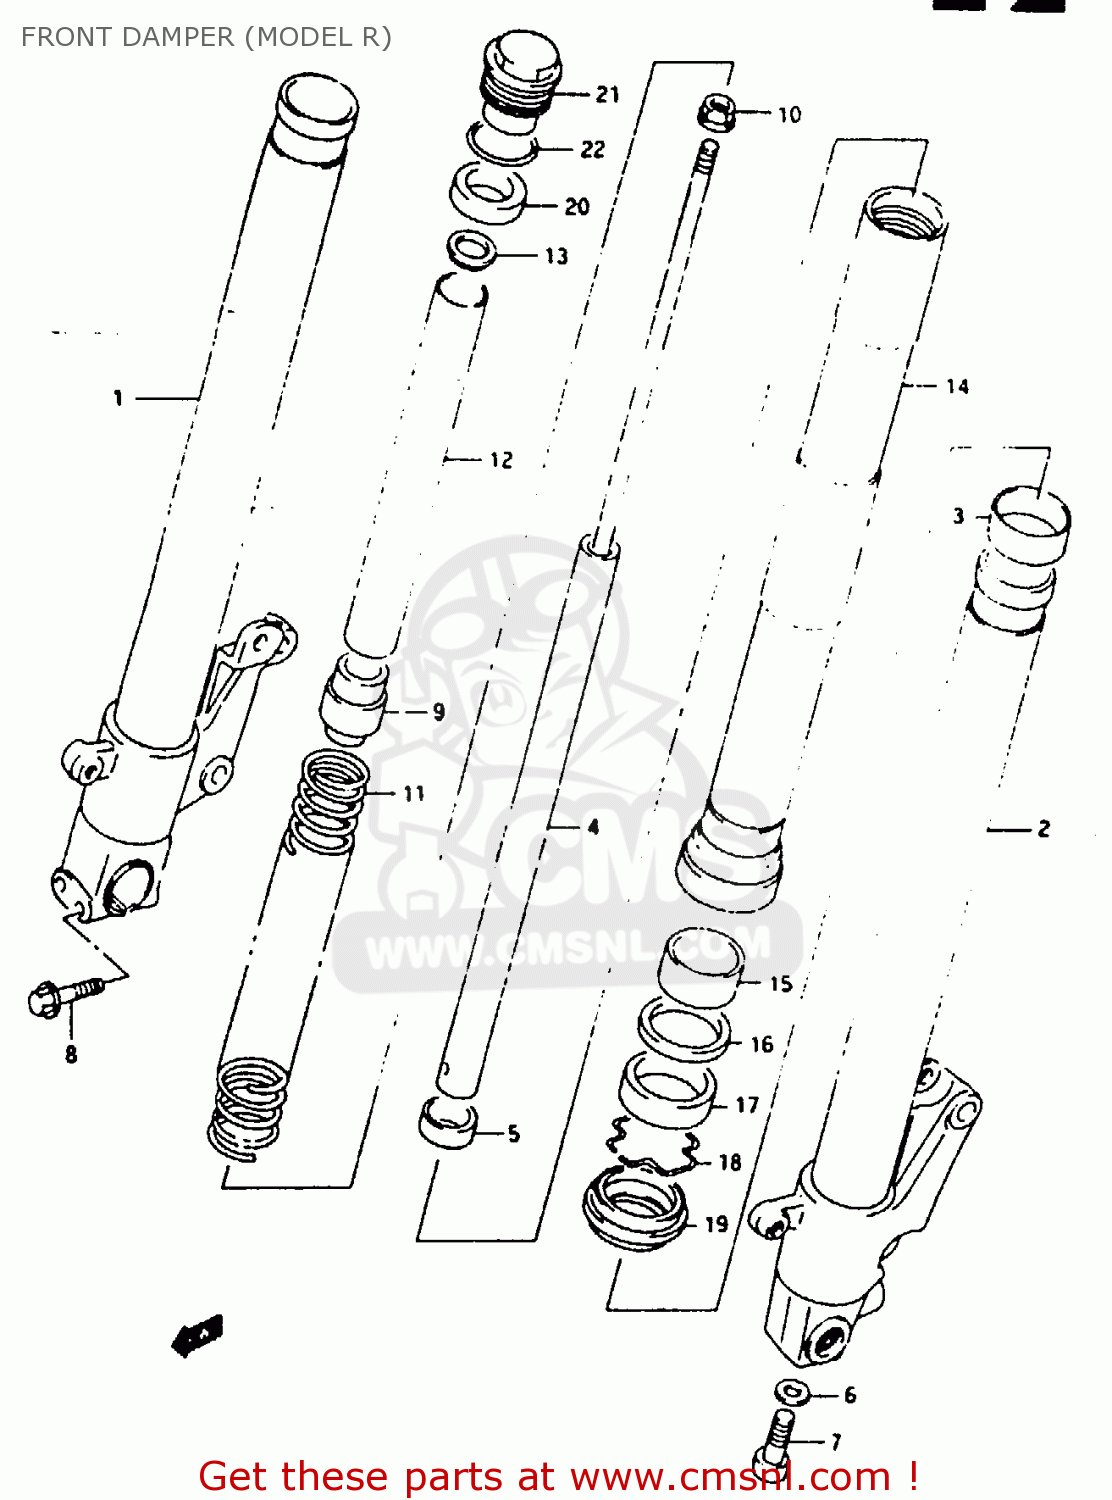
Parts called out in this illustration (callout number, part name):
1	TUBE,INNER,R
2	TUBE,INNER,L
3	BUSH,SLIDE
4	DAMPER, FRONT
5	PLATE,CENTERING
6	GASKET (NAS)
7	BOLT,CTR
8	BOLT
8A	RING,PISTON
9	JOINT,SPRING
10	NUT,INNER ROD
11	SPRING,MAIN
12	SPACER,SPRING
13	WASHER,UPR
14	TUBE, OUTER
15	GUIDE,BUSH
16	SPACER,SEAL
17	SEAL,OIL
18	RING,OIL SEAL STOPPER
19	SEAL,DUST
20	RUBBER,SEAT
21	BOLT,FORK
22	O RING,FORK BOLT
